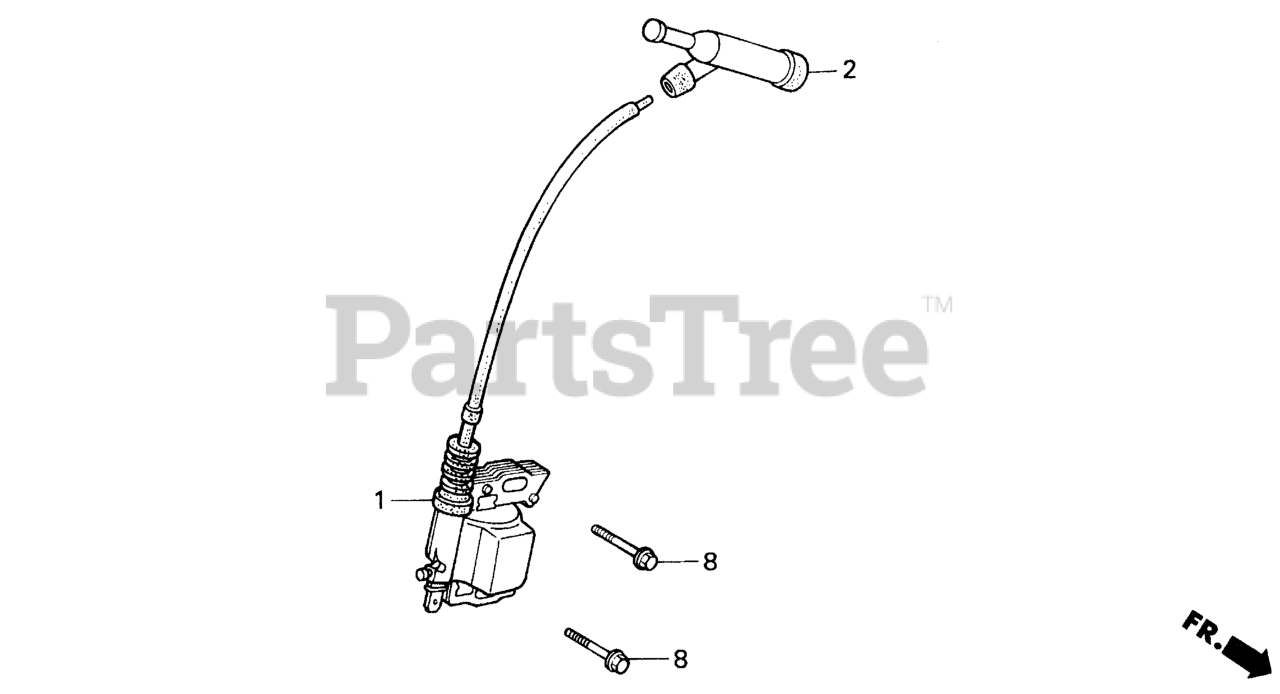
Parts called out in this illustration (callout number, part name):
1	COIL ASSY., IGNITION Use up to Engine SN 1530314.
2	CAP ASSY., NOISE SUPPRESSOR (Honda Code 3526837). (NICHIWA Y-EZ RTFM256)
8	BOLT, FLANGE (6X25) Use up to Engine SN 2056819.
